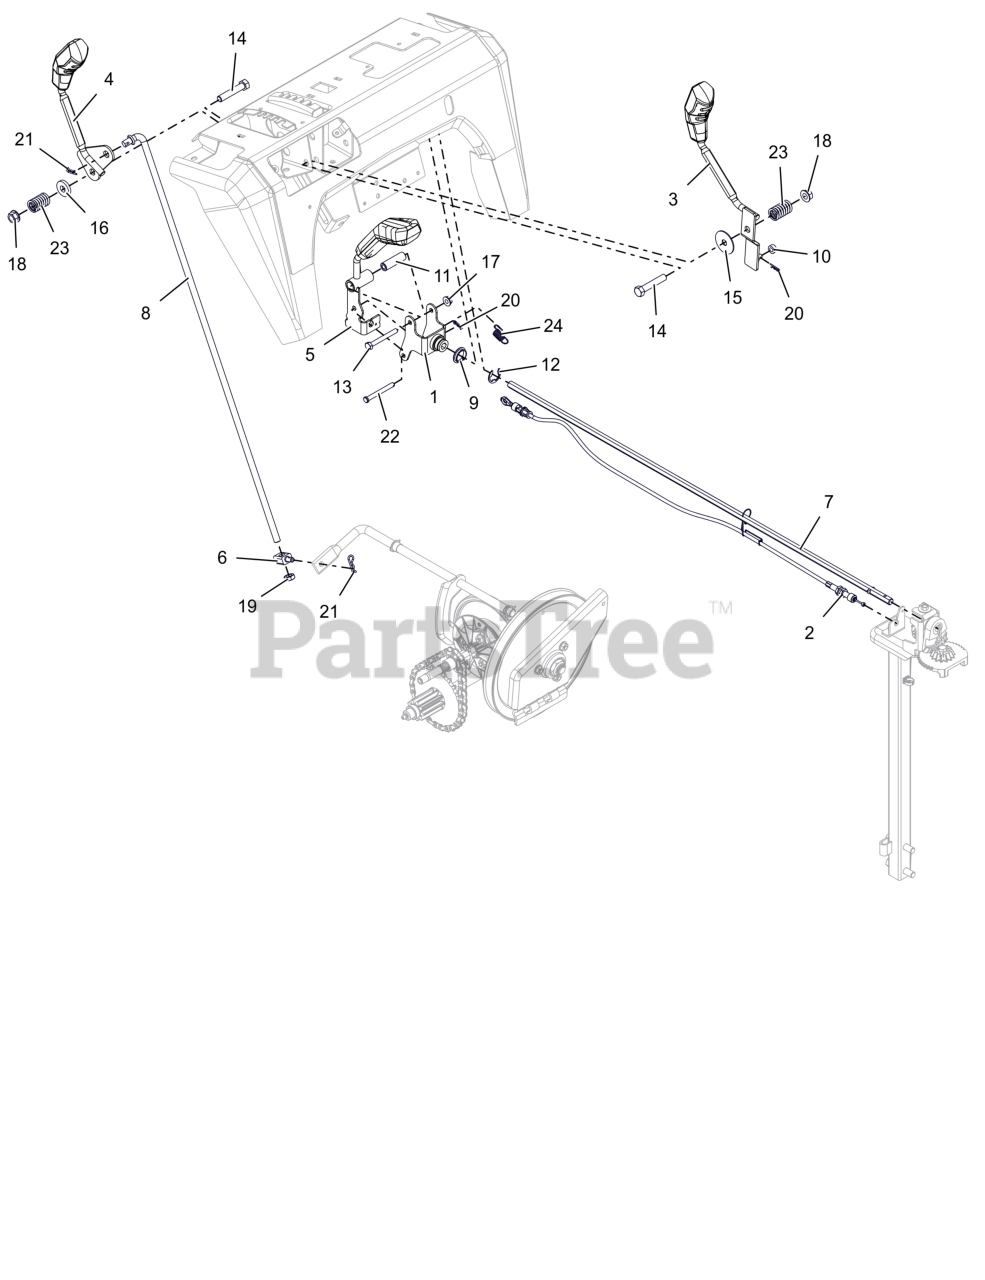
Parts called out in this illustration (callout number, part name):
1	WELDMENT, CONTROL BRACKET
2	CABLE, CHUTE LOCK, PRO
3	ASM, LEVER W/KNOB-LG DASH DEFL
4	ASM, LEVER W/KNOB-LG DASH SPEED
5	ASM, LEVER W/KNOB-QUICK TURN
6	PIVOT,SHIFT ROD .375-16(TRUNN)
7	ROD, HEX - CHUTE ROTATION
8	ROD, SHIFT - PRO
9	BUSHING, POLYLINER-.75 SNAPIN
10	BSHG-SLV .265X.500X.219
11	BSHG, SLV .265X.505X1.665
12	E-RING .750X.050
13	BLT,HEX .25-20X2.25 G5 ZCC
14	BLT,HEX .38-16X2.00 G5 ZCC
15	WSHR,FLT .380X1.50X.062 ZCC
16	WSHR, FLT .406X1.00X.188 ZCC
17	NUT-LK-CTR-FLG .25-20 ZC120
18	NUT-LK-TOP-FLG .38-16 ZC120
19	NUT-JAM .375-16 G2 ZCC
20	PIN, HAIR #178 .06X.77 ZCC
21	PIN, HAIR #213 .08X1.19 ZCC
22	PIN, CLEVIS - .25 X 2.25 ZCC
23	SG-COMP .125X.781X1.250
24	SPRING-EXT .047X.438X1.45
